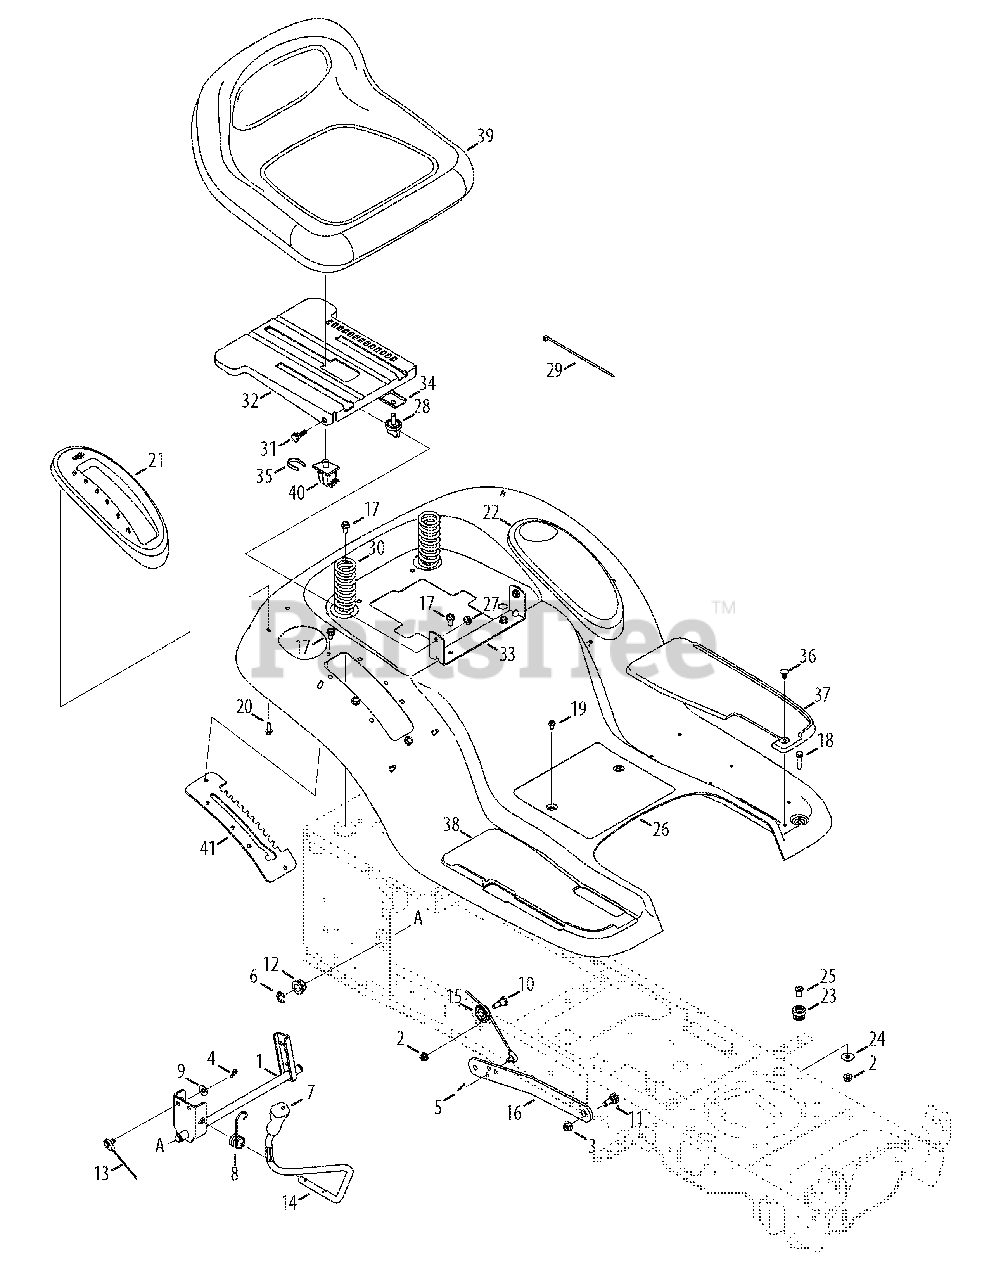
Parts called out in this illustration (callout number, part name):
1	Shaft Ass’y, Lift
2	Nut, Flange Lock, 5/16-18, Grf
3	Nut, Flange Lock, 3/8-16, Grf
4	Pin, Cotter, .072 Dia. x 1.13
5	Pin, Cotter, Bow-Tie 72
6	Ring, E Type, .625 Dia. Shaft
7	Grip, Handle, 1/2
8	Spring, Torsion
9	Washer, Spring, .401 x .870 x .063
10	Screw, Shoulder, .437 x .470, 5/16-18
11	Bolt, Shoulder, .500, 3/8-16
12	Bearing, Hex Flange
13	Cable, Lift, 16.16
14	Handle, Lift,
15	Pulley, Roller, Cable
17	Screw, Self-tapping, 5/16-18, .750,
18	Hex Screw, 5/16-18, 1.25, Gr5, Std
19	Screw, Self-tapping, 1/4-20, 0.500,
20	Screw, HL, 1/4-15, 0.750,
21	Cover, Lift Lever
22	Cover w/ Cup Holder
23	Grommet, .4375 ID x .750
24	Washer, Flat .344 x 1.00 x .063
25	Spacer, Flange, .3125 x .4375 x .625
27	Nut, Flange Lock, 5/16-18, Gr5, Sd Lk
28	Knob, 3/8-16, .875
29	Cable, Tie, 3/16 x .05 x 7.4
30	Spring, Comprs, 1.71 x 3.735 x .238
31	Screw, Shoulder, .437 x .268, 5/16-18
32	Bracket, Mounting, Seat
33	Bracket, Pivot, Seat
34	Bracket, Knob Adjustment, Seat
35	Clip, Retaining, Switch
36	Clip, Ratchet, .250 Dia
37	Pad, Foot, LH
38	Pad, Foot, RH
39	Seat, Medium Back
40	Switch, Seat
41	Bracket, Lift, Manual PTO, 6 Pos
